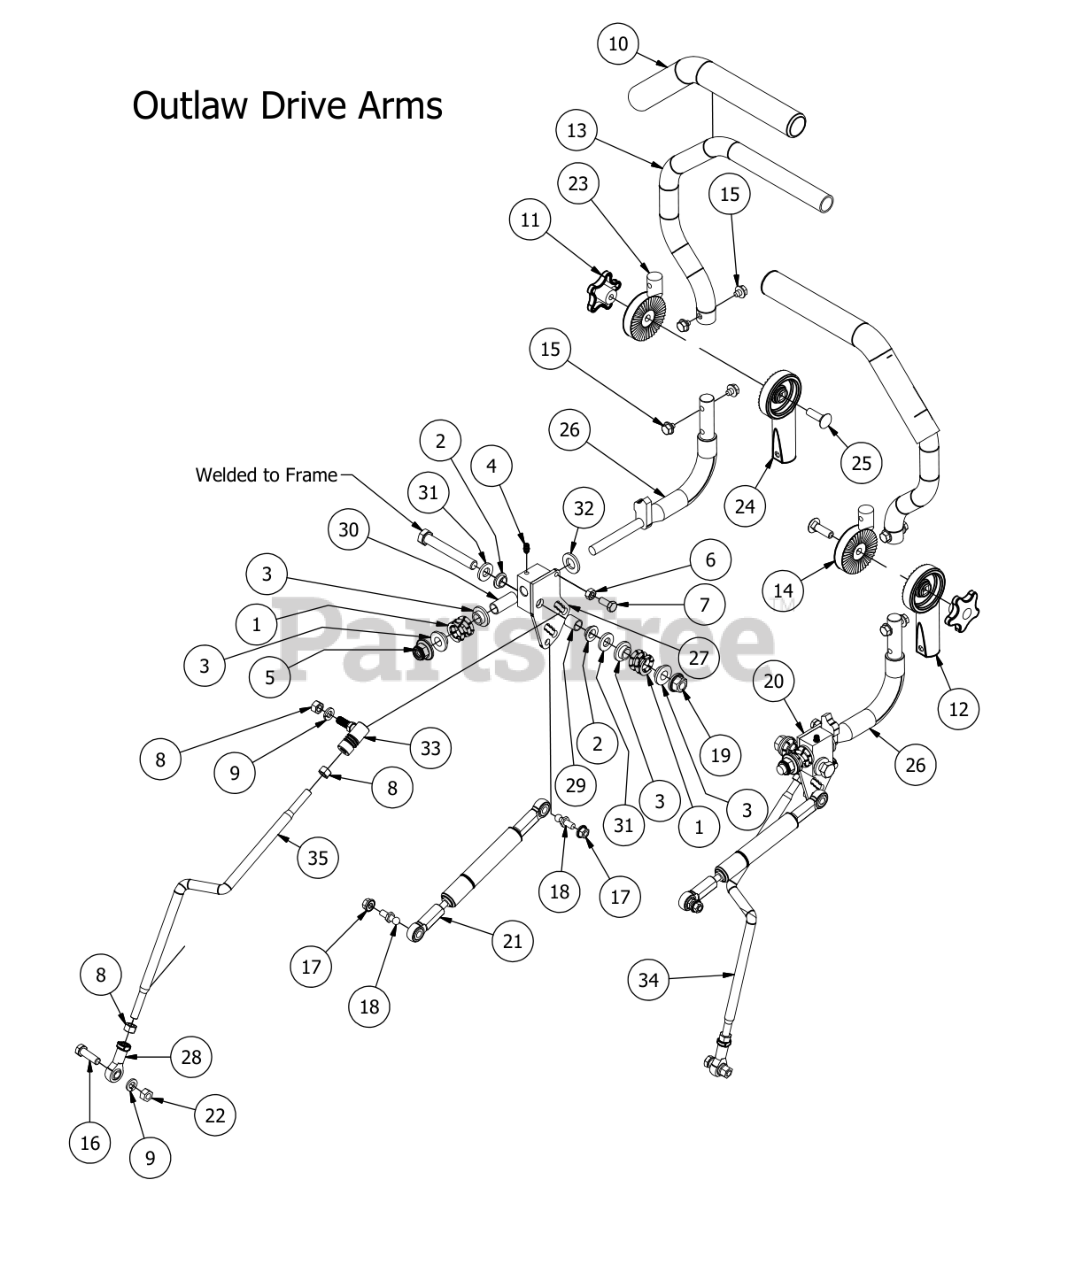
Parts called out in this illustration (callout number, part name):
1	Drive Lever Spring
2	Bushing for 2012 Drive Arms
3	.515 ID Nylon Shoulder Washer
4	1/4" Press in Grease Fitting
5	1/2-13 Nylon Flange Nut
7	5/16" x 3/4" Hex Bolt
8	3/8" Fine Threaded Jam Nut
9	3/8" Lock Washer
10	Black Steering Grip
11	Black Knob for Adjustable Steering Arm
12	Lower Adjuster - Steering Arm- Right
13	Upper Tube-Adjustable Steering
14	Upper Adjust Steering Arm- Right
15	5/16-18 1/2 HWH Bolt-Steering
16	3/8" x 1 1/4" Hex Bolt
17	5/16" Flange Nut
18	10mm Damper Ball Stud-Steering
19	1/2-13 Mechanical Lock Nut Grade F
20	2013 Drive Lever Housing (Right)
21	Steering Damper
22	3/8-16 Hex Nuts Zinc
23	Upper adjuster-Steering Arm- Left
24	Lower Adjuster - Steering Arm- Left
25	3/8" x 1 1/4" Carriage Bolt
26	Steering Arm Elbow - Right
27	2013 Drive Lever Housing (Left)
28	Spherical Rod End - Outlaw
29	Drive Arm Block Insert-short
30	Drive Arm Block Insert-long
31	.505x1x .125 Oil Impregnated washer
32	.630 ID Plastic Washer
33	Quick Release Ball Joint
34	2015 Outlaw Push Rod - Right
35	2015 Outlaw Push Rod - Left
